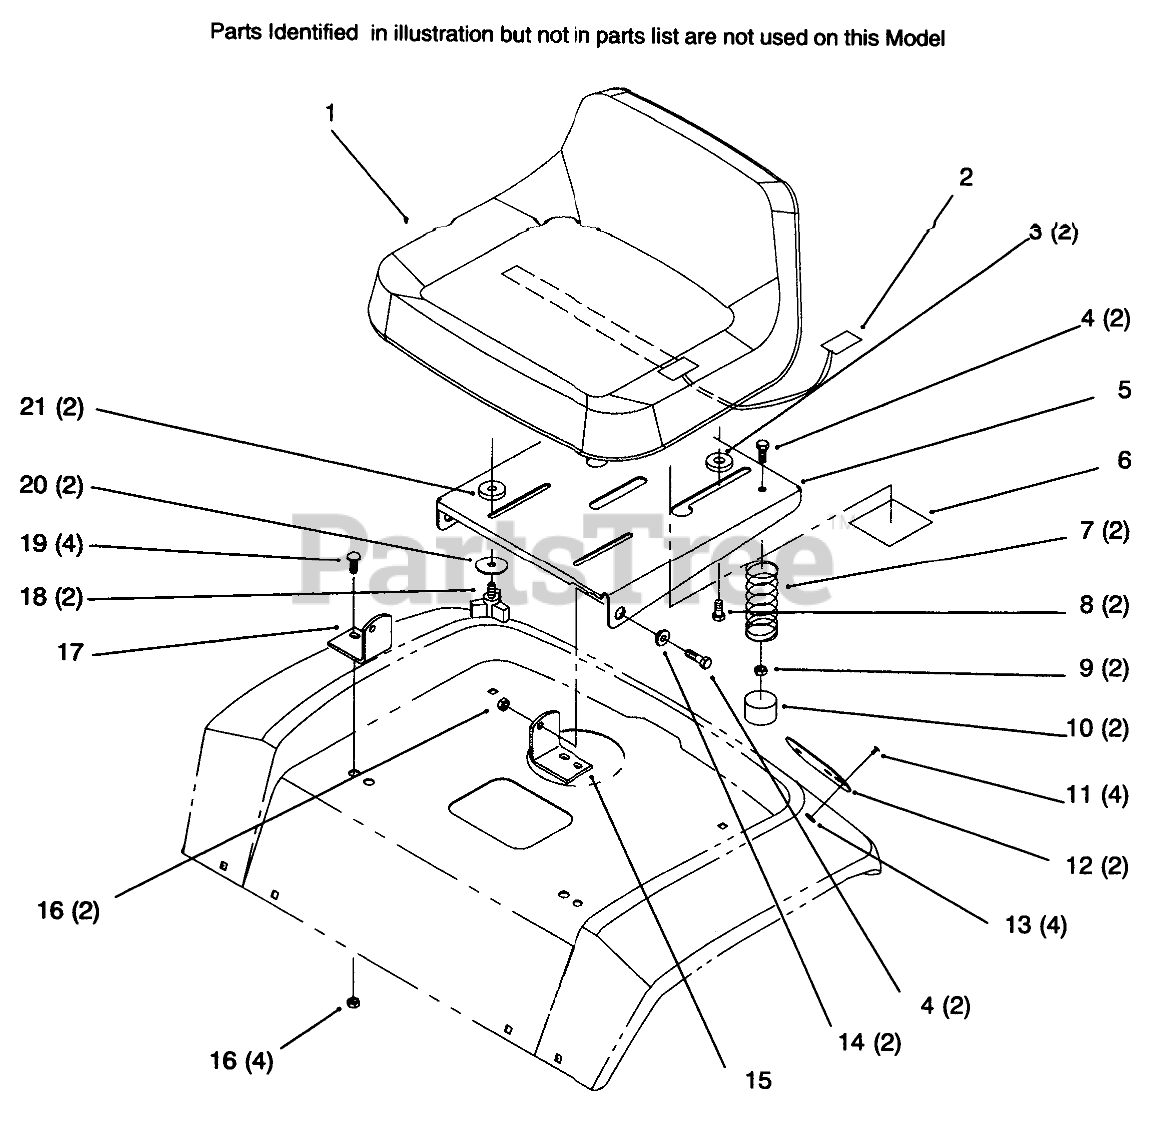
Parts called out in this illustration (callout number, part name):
1	SEAT
2	SWITCH-SEAT
3	SPACER-NYLON
4	SCREW-HH
5	SUPPORT - SEAT (BLACK)
7	SPRING-COMPRESSION
8	BOLT-SHOULDER
9	NUT-LOCK, NI
10	CAP-PROTECTOR
11	RIVET-BLIND
12	REFLECTOR-STICK ON
13	WASHER-PLAIN
14	BUSHING
15	BRACKET-PIVOT, LH
16	NUT-LOCK, NI
17	BRACKET-PIVOT, RH
19	BOLT-CARR
20	WASHER
21	SPACER-NYLON
